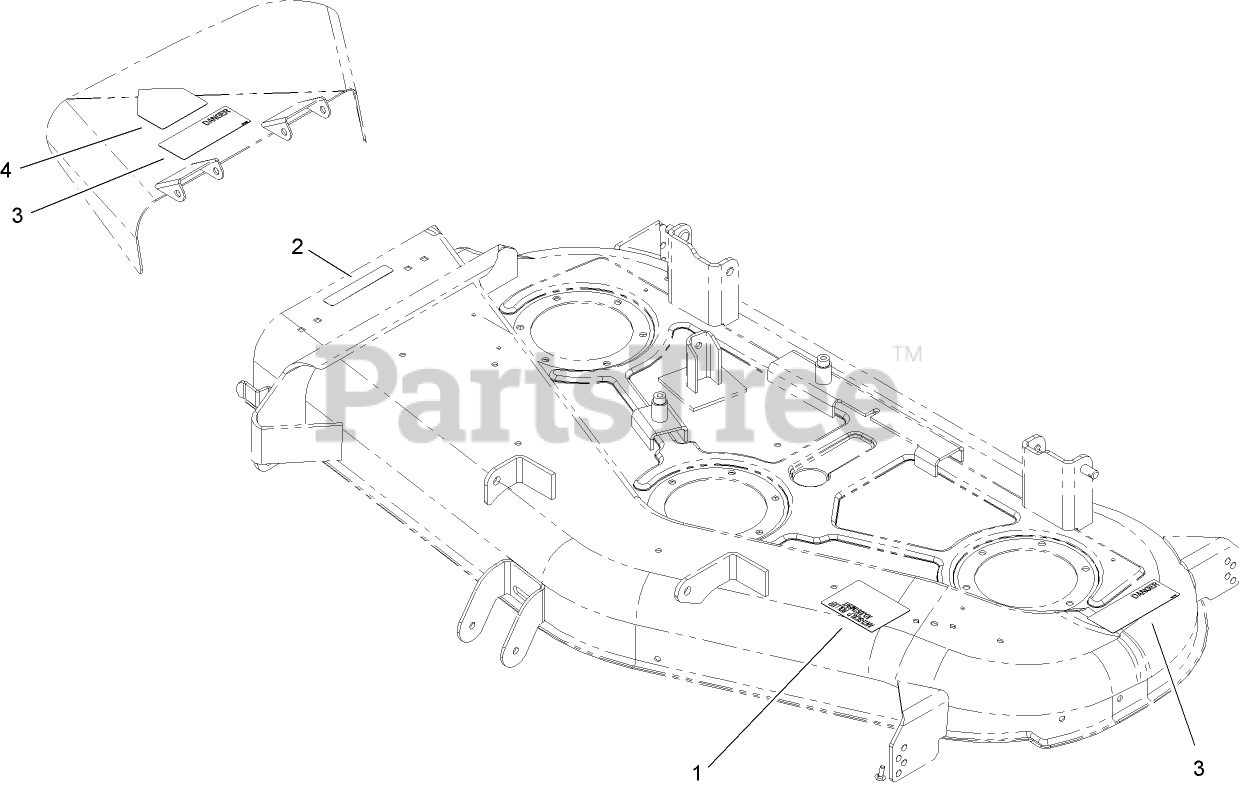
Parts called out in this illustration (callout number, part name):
1	DECAL-ANTI SCALP
2	DECAL-DANGER
3	DECAL-DANGER
4	DECAL-DANGER, SHIELD
